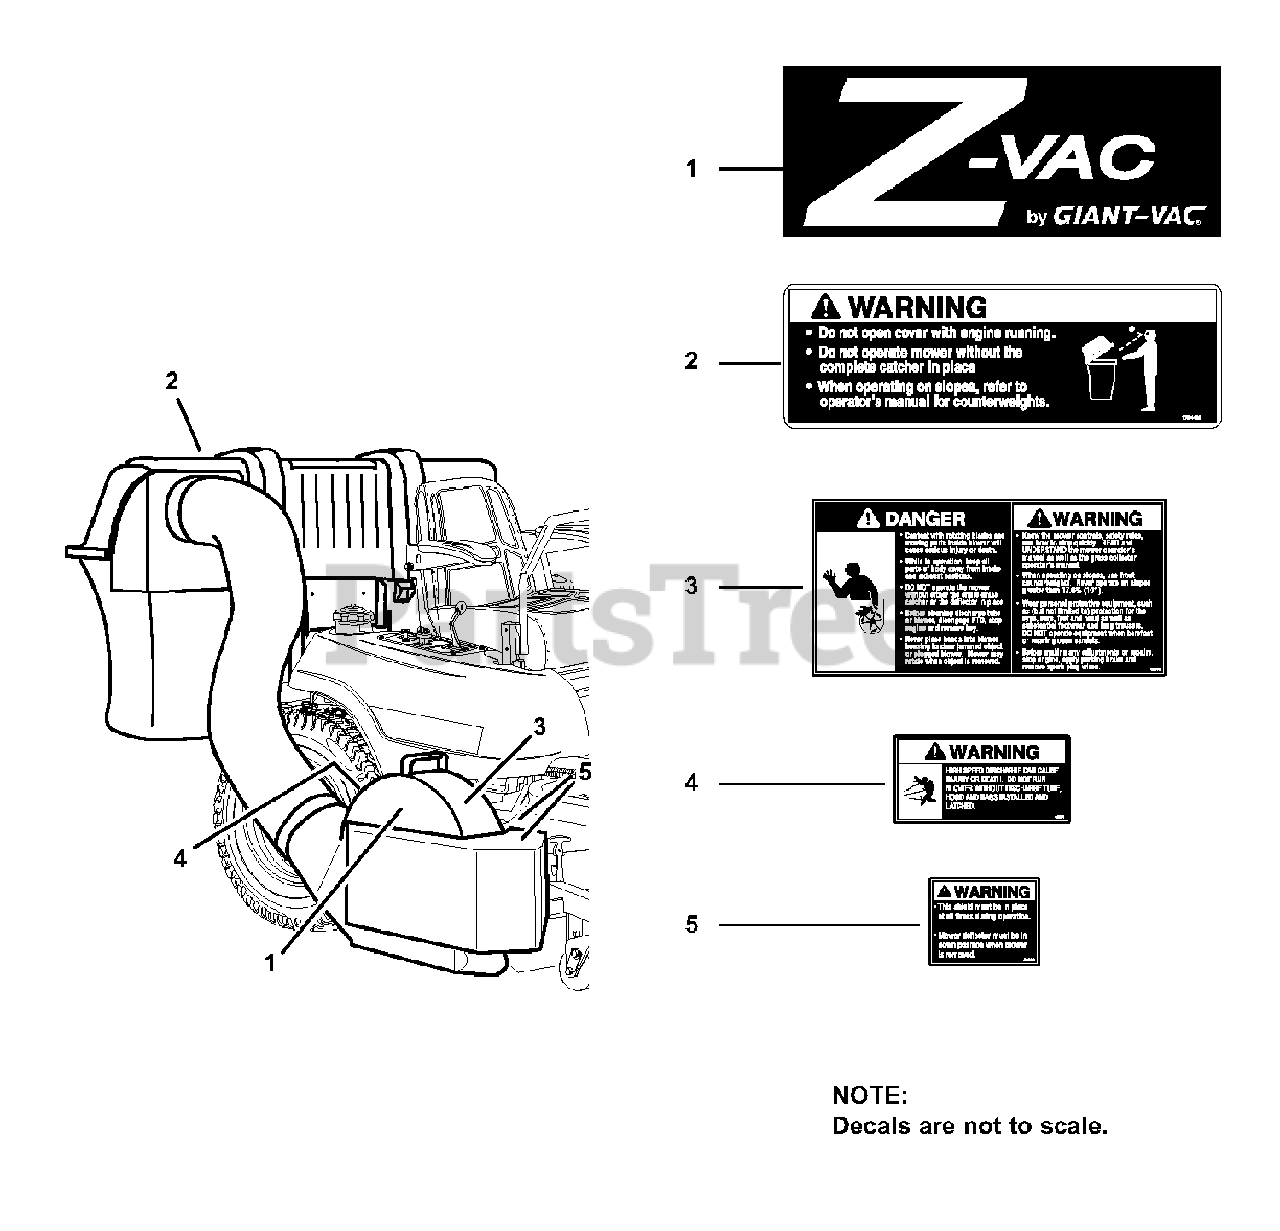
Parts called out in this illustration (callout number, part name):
1	DECAL, Fast-Vac
2	DECAL, Safety, Grass Bag
3	DECAL, Danger, Fast-Vac
4	DECAL, Warning, Fast-Vac
5	DECAL, Warning, Fast-Vac
